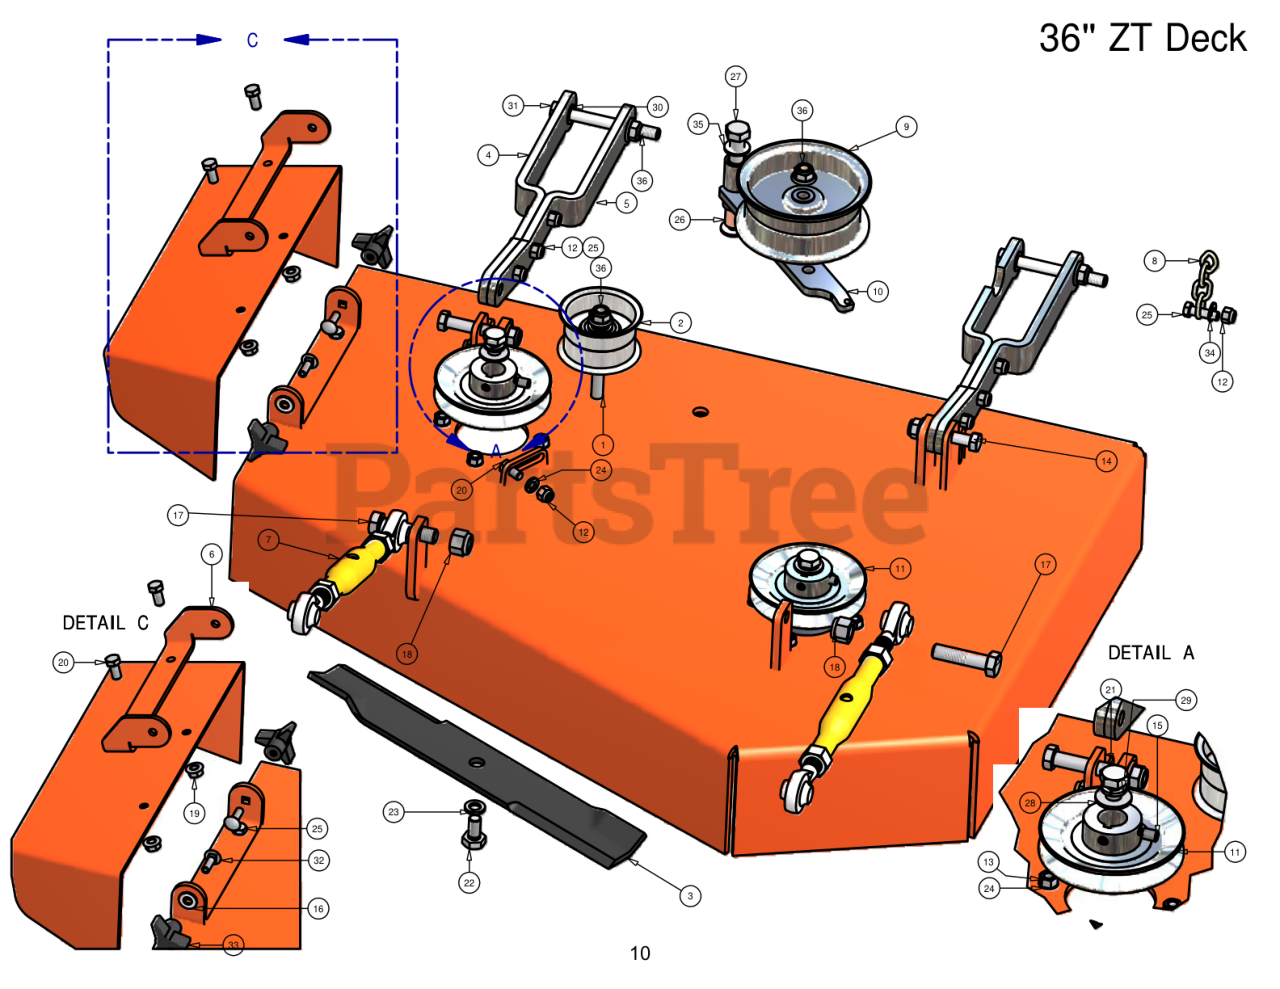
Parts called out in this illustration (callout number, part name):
1	36 Inch ZT Deck
2	36" ZT Idler Pulley
3	36" Fusion Blade
4	Deck Support Arm (left)
5	Deck Support Arm (Right)
6	Discharge Chute Bracket
7	Turnbuckle
9	5 3/4" Flat Idler Pulley
10	Deck Idler Arm
11	5" Deck Pulley
12	3/8" Nylock Nut
13	3/8" Hex Nut
14	1/2" x 2 1/2" Hex Bolt
15	3/8" Set Screw
16	.360 ID Plastic Washer
17	5/8" x 2 1/2" Hex Bolt
18	5/8" Nylock Nut
19	3/8" Flange Nut
20	3/8" x 3/4" Hex Bolt
21	1/2" x 1 1/2" Fine Threaded Bolt
22	5/8" x 1 1/2" Fine Threaded Bolt
23	5/8" Lock Washer
24	3/8" Lock Washer
25	3/8" x 1 1/4" Hex Bolt
26	5/8" ID × 1 1/8" Brass Bushing
27	5/8" x 4" Hex Bolt
28	1/2" Cup Washer
29	1/2" Lock Washer
30	1/2" Brass Washer
31	1/2" x 4 1/2" Bolt
32	5/16" x 1" Carriage Bolt
33	5/16" Knob
34	3/8" Washer
35	.635 Nylon Washer
36	1/2" Flange Lock Nut
